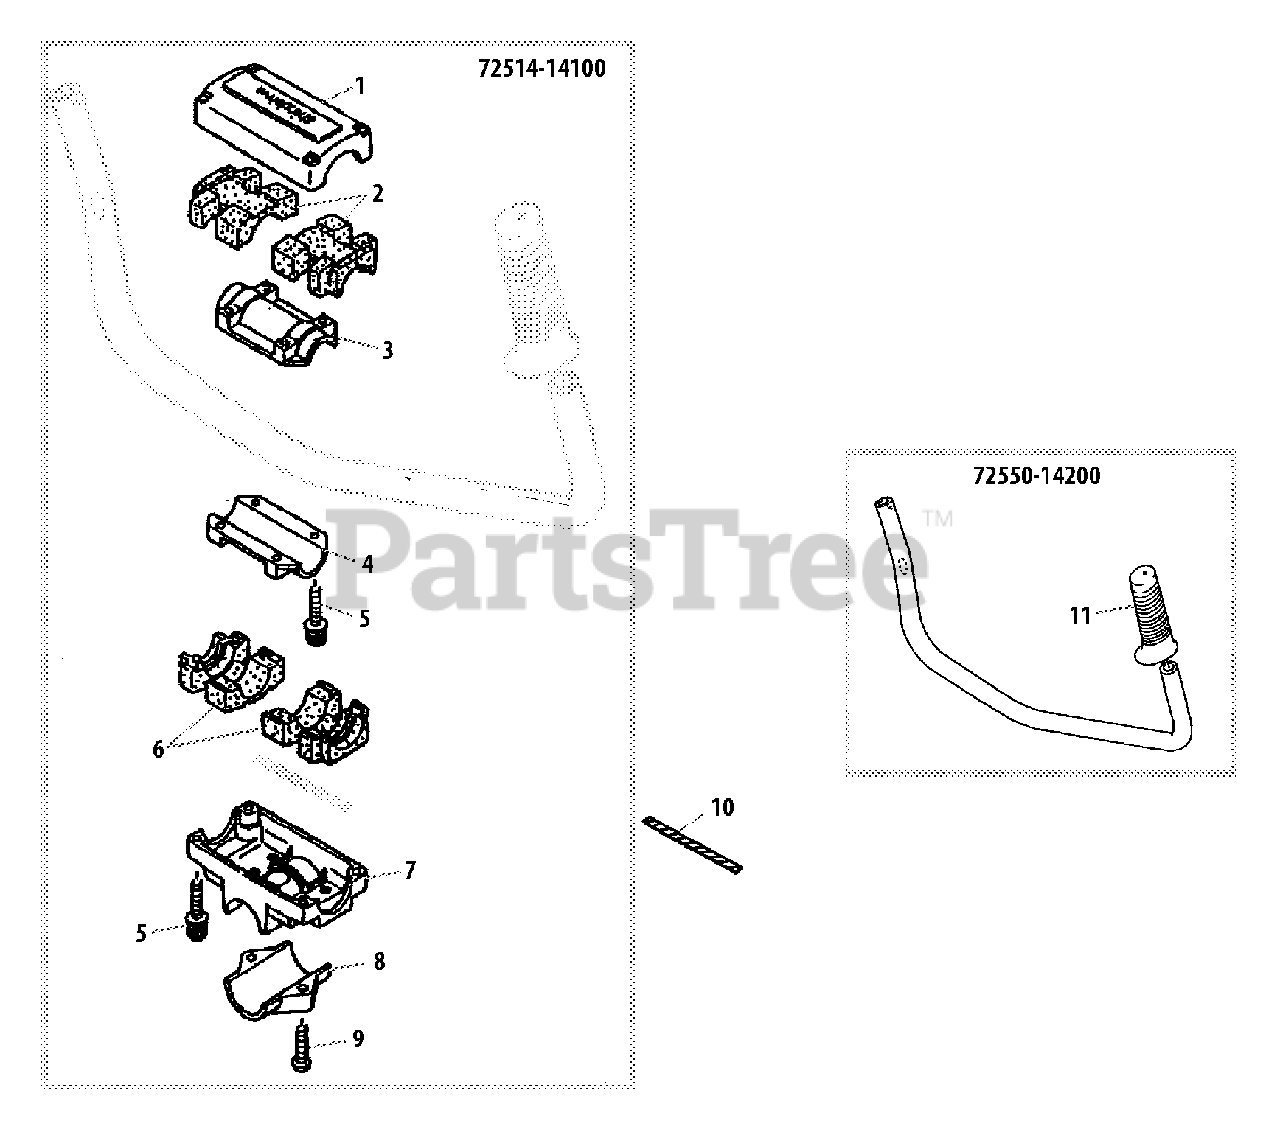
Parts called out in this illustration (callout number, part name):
1	CLAMP, UPPER
2	CUSHION, UPPER
3	CLAMP, UPPER
4	CLAMP, LOWER
5	BOLT M5×25
6	CUSHION, LOWER
7	BRACKET, HANDLE Ø28
8	CLAMP, LOWER Ø28
9	SCREW M6×25
10	LEAD - GROUND
11	GRIP
72514-14100	HANDLE BRACKET KIT
72550-14200	HANDLEBAR ASSY
